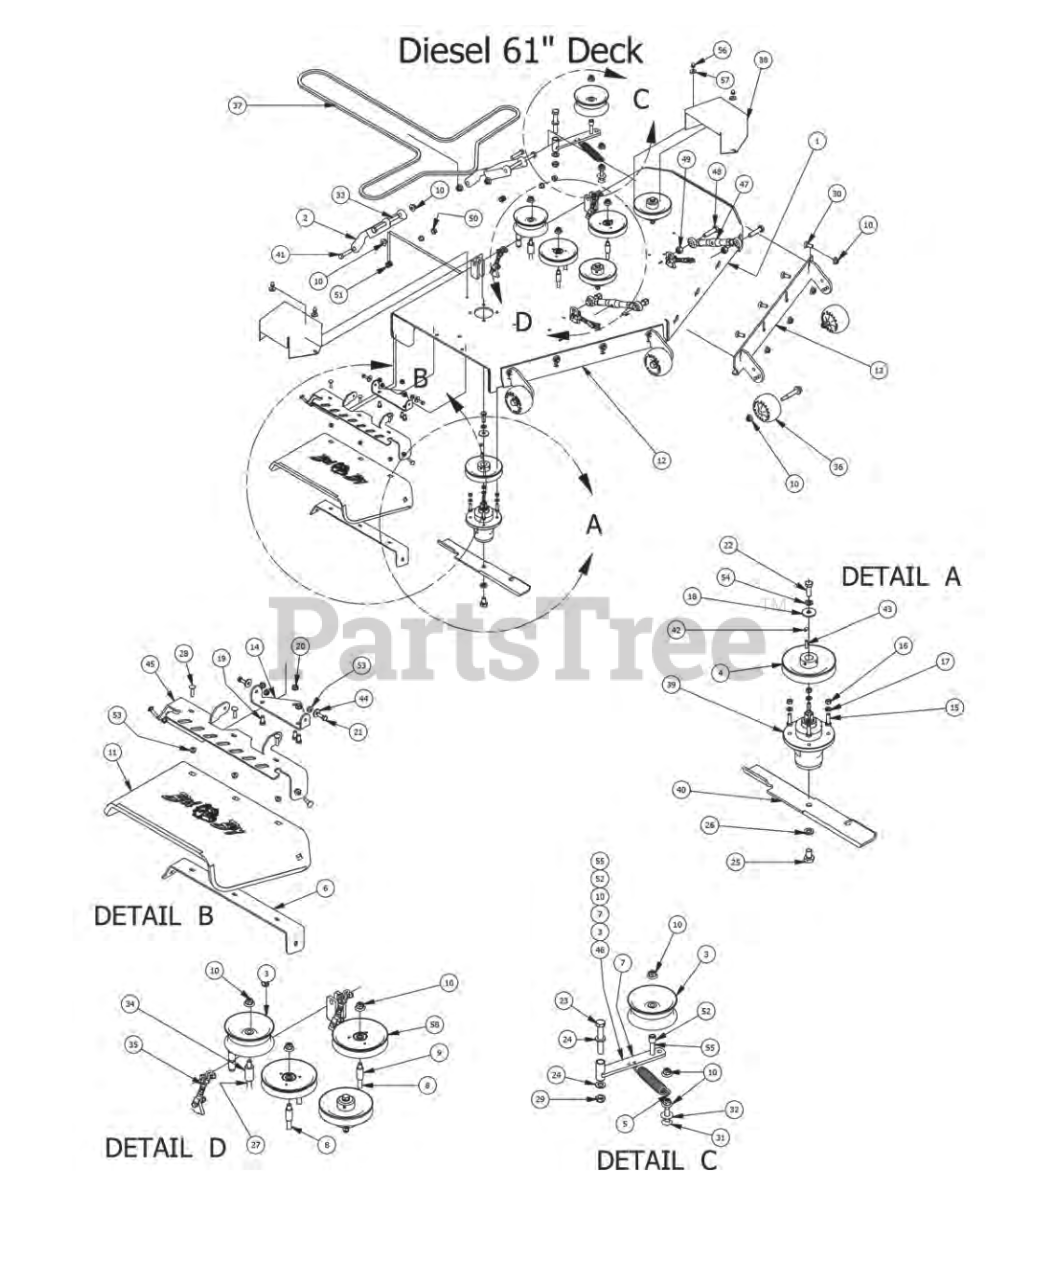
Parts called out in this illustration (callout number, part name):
1	51" AOS Deck
2	Deck Arm Assembly
3	5.3/4" Deck Idler Pulley
4	6 1/4" Drive Pulley
5	2009 Deck/Pump Idler Spring
6	60" Discharge Lower Bracket
7	Deck Idler
8	1/2 x 3 1/2 Flange Bolt Grade 8
9	502 ID X,75 OD X 1.500 Leng
10	1/2-13 Nylon Insert Flange Nut
11	Rubber Discharge Chute
12	61 Outlaw Adjustable Deck Front (Left)
13	61 Outlaw Adjustable Deck Front (Right)
14	Discharge Chute Hanger (deck mounted)
15	3/6 x 1 1/4" Hex Bolt
16	3/8-16 Hex Nuts Zinc
17	3/8 Lockwasher Zinc
18	1/2 Belleville Washer
19	3/8" x 3/4" Hex Bolt
20	3/8" Flange Nut
21	5/16" x 1" Bolt
22	1/2"-20 x 1 1/2-Grade 5 Fine Thread Bolt
23	5/8" x 4" Hex Bolt
24	.635 ID Plastic Washer
25	5/8 x 1 1/2" Gr8 Hex Bolt (Fine)
26	5/8" Lock Washer
27	1/2" x 4" Bolt (Grade 8)
28	5/16" x 1 1/4" Carriage Bolt
29	5/8-11 Nylon Insert Jam Half Nut
30	1/2 x 1 1/4 Carriage Bolt
31	1/2 x 2" Carriage Bolt
32	517 Square Hole Round Washer
33	1/2" x 5 1/2" Bolt
34	1 3/4" Pulley Spacer
35	4-Link Adjustable Deck Hange
36	Anti-Scalp Rollers
37	B236 Belt-Diesel EZ Ride
38	Pulley Cover
39	Double Bearing Spindle
40	61 inch Fusion Blade
41	1/2-13X 2-1/4 GR Hex Bolts
42	5/16 Set Screw
43	1/4" x 1" Key
44	360 ID Plastic Washer
45	60" Discharge Chute Upper Hanger
46	Deck Idler Assembly-parts of Assembly 4,9,12,63,67
47	Turnbuckle (Top Link)
48	5/8" x 2.1/2" Gr5 Hex Bolt (Coarse)
49	5/8 Std NC Nylock Nut
50	Flange Bushing For Deck Arm upper
51	Flange for Lower Deck Arm
52	3/4 OD x 1/2 ID x 314 Length
53	5/16" Nylon Flange Nut
54	1/2" Lock Washer
55	1/2-13 x GR 5 Hex Bolt Zin
56	Acorn nut-pulley Cover
57	360 ID Plastic Washer-Black
58	5-3/4 Idler Pulley
